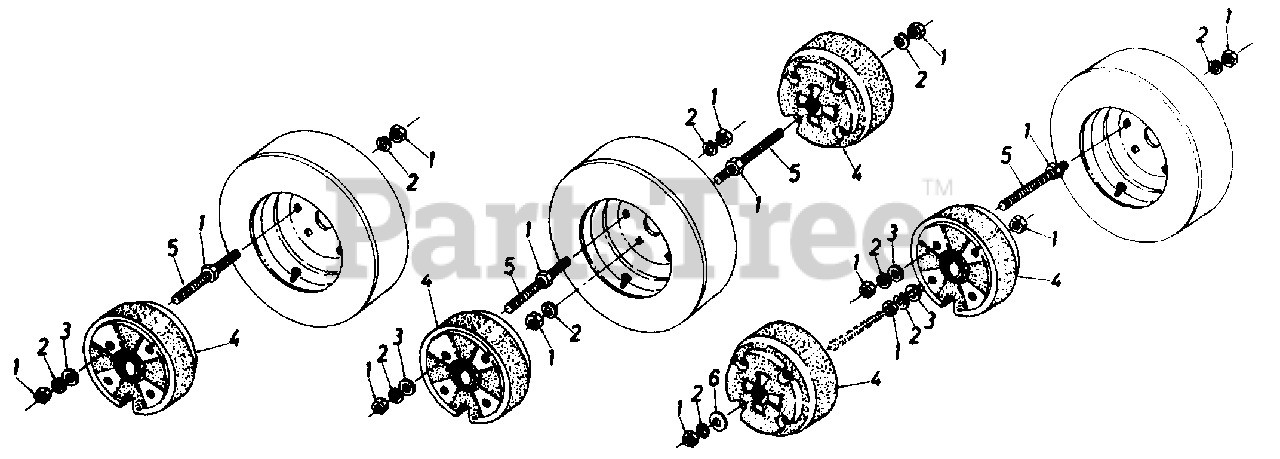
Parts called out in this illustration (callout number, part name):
1	Hex Nut 1/2-13 Thd.
2	Lock Wash. 1/2" I.D.
3	Fl-Wash. .53" I.D. x .93" O.D.
4	Wheel Weight
5	Rod Threaded 1/2-13 x 9.5" Lg.
6	Fl-Wash. .5" I.D. x 2.0" O.D.
